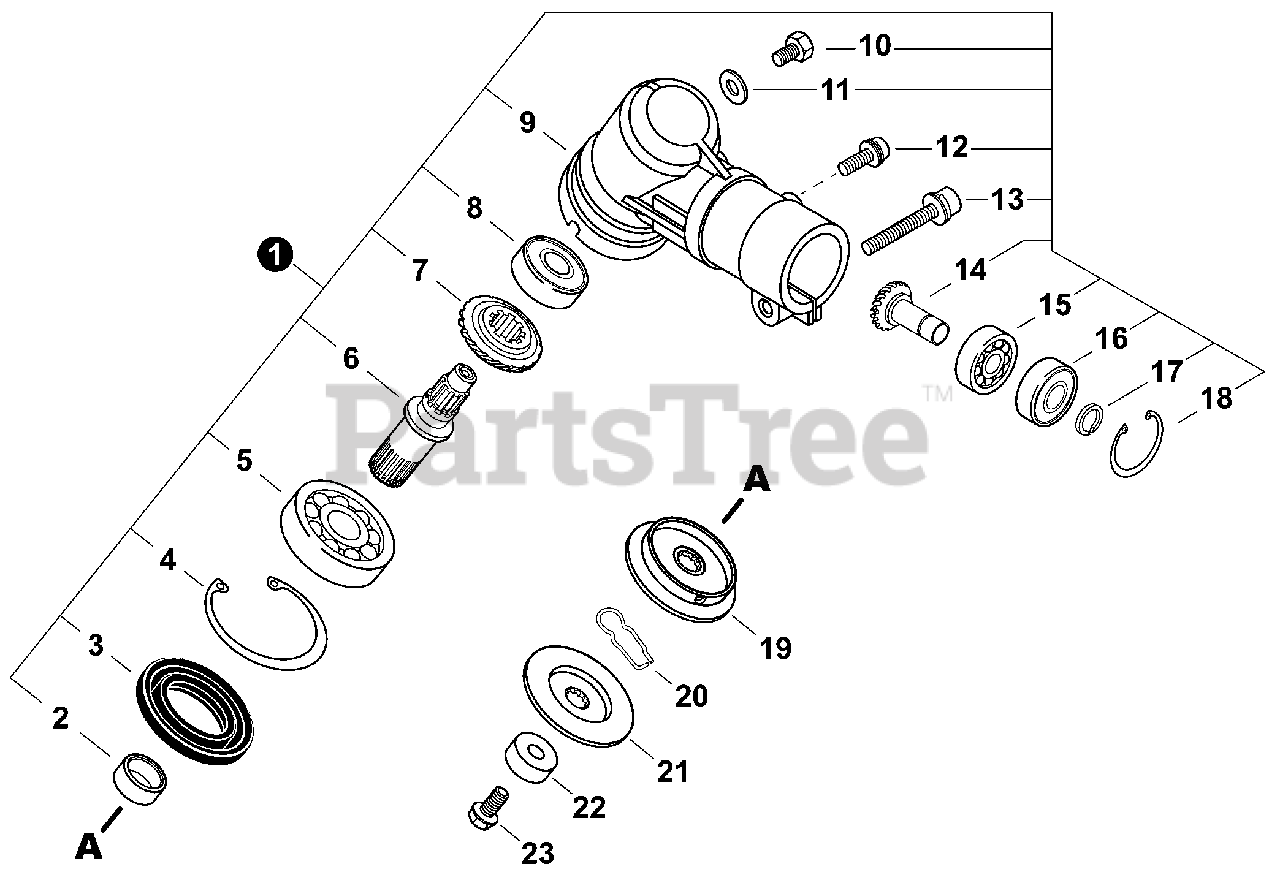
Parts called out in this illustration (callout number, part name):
1	GEAR CASE ASSY
2	COLLAR
3	SEAL, OIL
4	RING, SNAP Ø35
5	BEARING, BALL 6202
6	SHAFT, GEAR
7	GEAR, BEVEL
8	BEARING, BALL 6000DDU
9	HOUSING, GEAR CASE
10	BOLT M6×10
11	WASHER
12	BOLT M6×14
13	BOLT M6×28
14	PINION ASSY, BEVEL
15	BEARING, BALL 6001
16	BEARING, BALL 6001ZZ
17	RING, SNAP Ø12
18	RING, SNAP Ø28
19	PLATE, ADAPTOR - UPPER
20	PIN, SLIDE
21	PLATE, ADAPTOR - LOWER
22	GUARD, BOLT
23	BOLT 10×30
